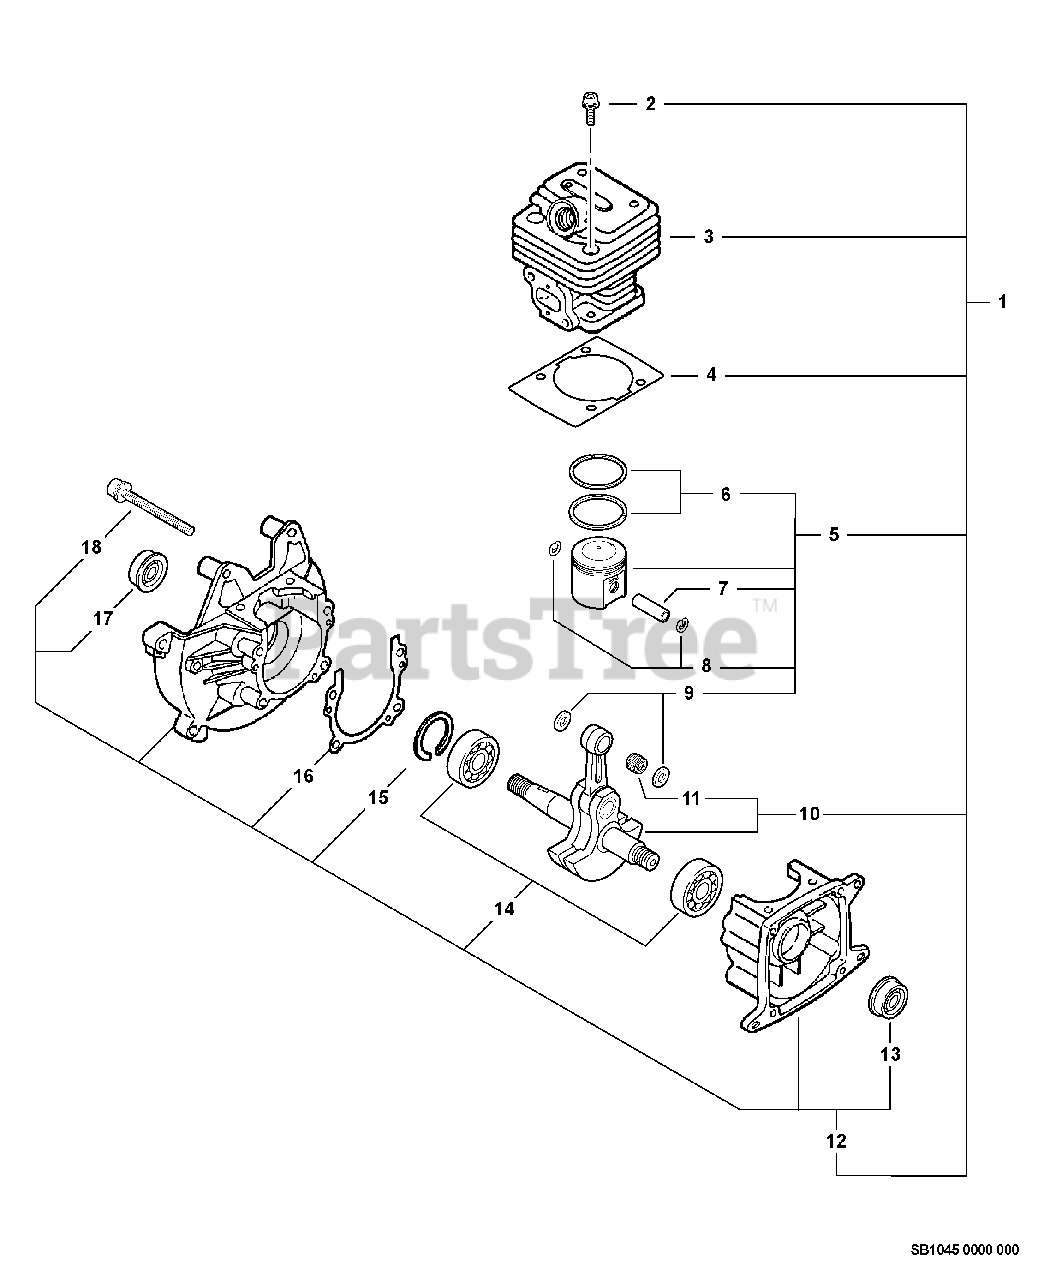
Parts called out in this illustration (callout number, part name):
1	SHORT BLOCK
2	BOLT 5×22
3	CYLINDER
4	GASKET, CYLINDER
5	PISTON KIT
6	RING, PISTON
7	PIN, PISTON 8
8	RING, SNAP
9	WASHER, THRUST
10	CRANKSHAFT ASSY
11	BEARING, NEEDLE 8
12	CRANKCASE KIT
13	SEAL, OIL 12
14	BEARING, BALL 6001
15	RING, SNAP 28
16	GASKET, CRANKCASE
17	BOLT 5×25
18	SEAL, OIL 12
